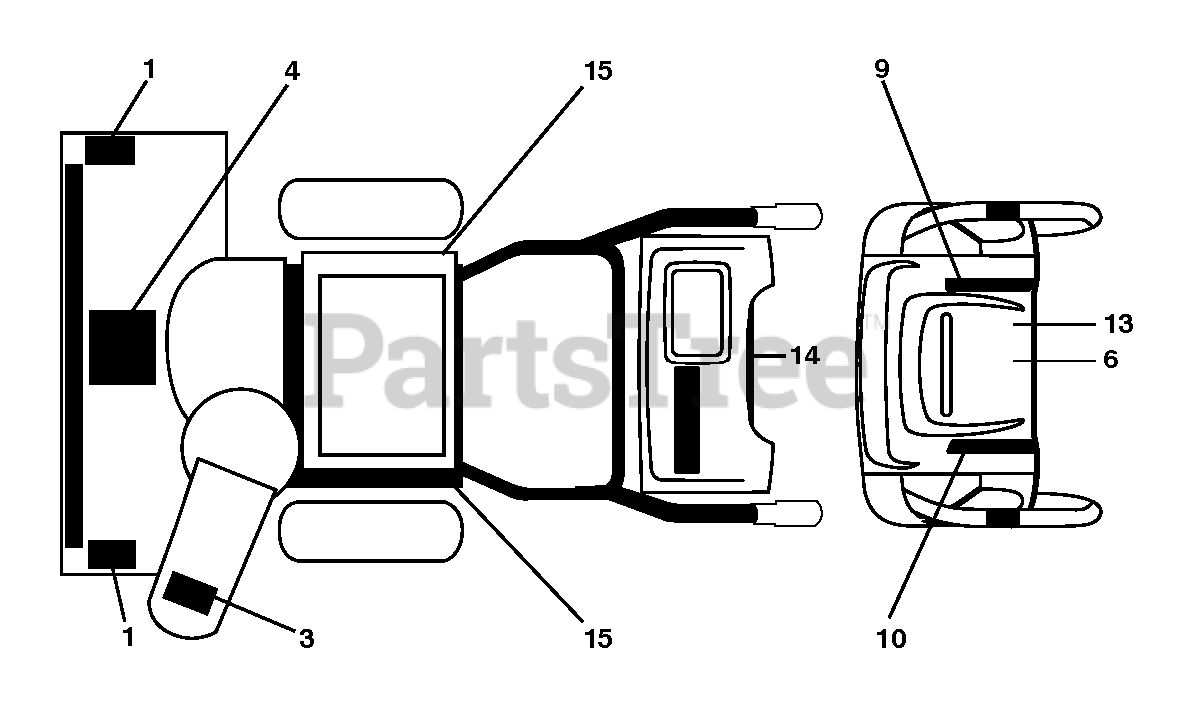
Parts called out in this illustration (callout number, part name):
1	DECAL.AUGER.SAFETY.
3	DECAL.CHUTE.SAFETY.EU/SC.17
4	DECAL.AUGER."
9	DECAL CONSOLE DECAL DECAL.SNOW
10	DECAL CONSOLE DECAL DECAL.SNOW
13	DECAL.CONSOLE.HAND.WARMER
14	DECAL.NOISE.LEV.105/CE.EAC.UKR
15	DECAL.BELT.GUARD.
